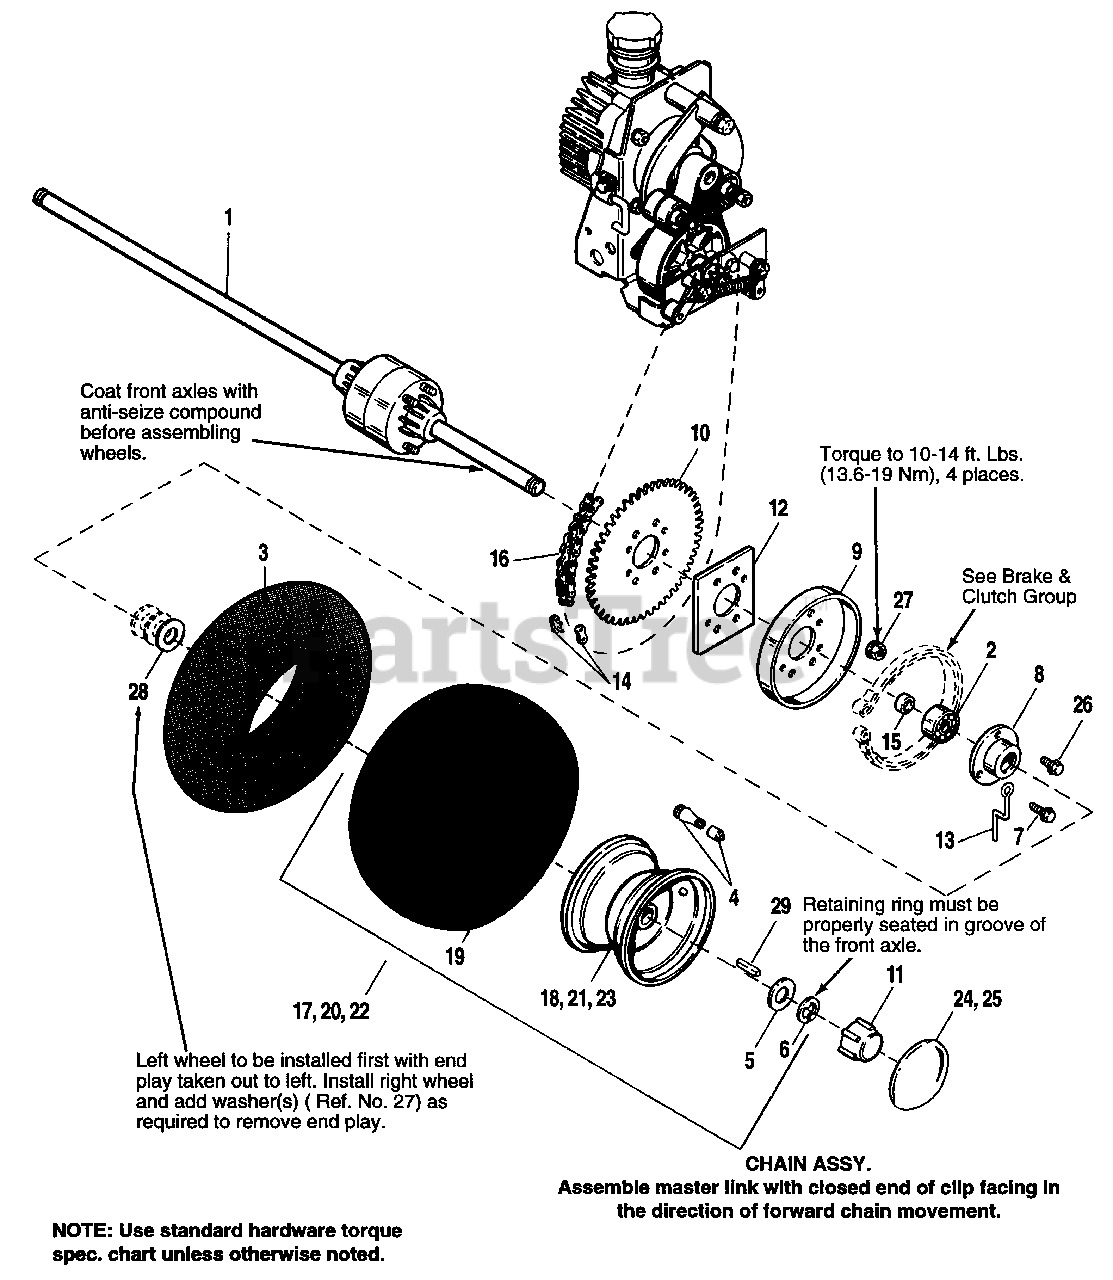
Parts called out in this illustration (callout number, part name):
1	AXLE ASSY., Differential (See pages 54 & 55 for service parts)
3	TUBE (Service only, see note below)
4	VALVE STEM & CAP
5	WASHER, 3/4
6	RING, Retaining, Wheel
7	SCREW, Taptite, 5/16-18x3/4
8	FLANGE, Bearing
9	DRUM, Brake
10	SPROCKET, 54 Tooth
11	CAP, Threaded (Not used on export models)
12	SHIM, Sprocket
13	STOP, Brake Band
14	MASTER LINK, Chain #40
15	SPACER, Axle
16	CHAIN, Roller, #40 x 63 pitches
17	WHEEL & TIRE ASSY., Silver, 5-3/8" wide x 8" dia. (Incl. Ref. Nos. 4, 18 & 19)
18	WHEEL ASSY., Silver, 5-3/8" wide x 8" dia.
19	TIRE, Dico, Turf Trac, 16 x 6.50-8
20	WHEEL & TIRE ASSY., White, 5-3/8" wide x 8" dia. (Incl. Ref. Nos. 4, 19 & 21)
21	WHEEL ASSY., White, 5-3/8" wide x 8" dia
22	WHEEL & TIRE ASSY., Metallic Gray, 5-3/8" wide x 8" dia. (Incl. Ref. Nos. 4, 19 & 23)
23	WHEEL ASSY., Metallic Gray, 5-3/8" wide x 8" dia.
24	HUBCAP, 8", Smooth
25	HUBCAP, 8", Scalloped
26	SCREW, Taptite, 5/16-18 x 1/2
27	NUT, Hex, Whizlock, 5/16-18
28	WASHER, Shim, 3/4 x 1-1/6 (Use as needed)
29	KEY, 3/16 x 3/16 x 1-1/2
